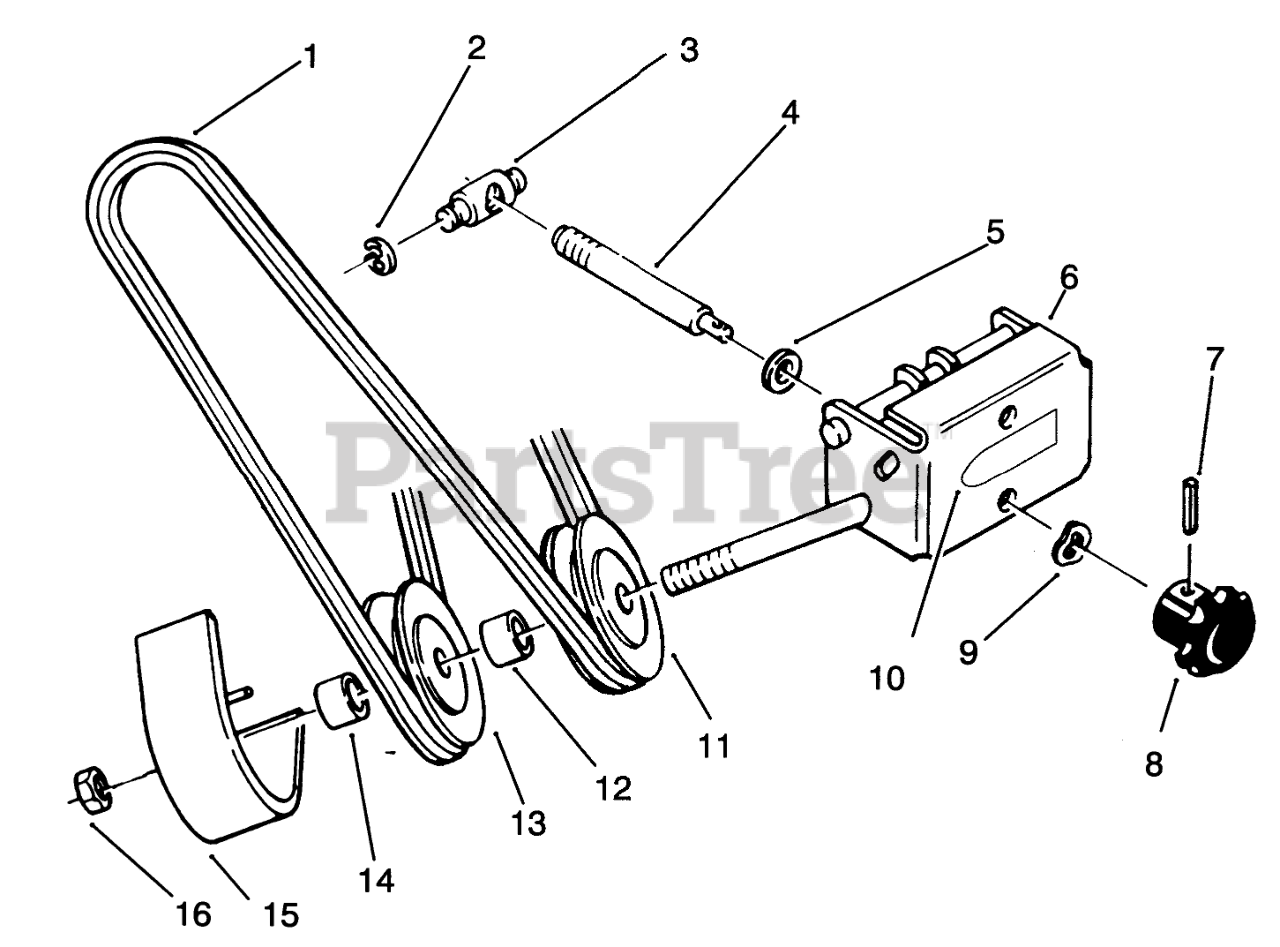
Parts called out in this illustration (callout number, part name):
1	V-BELT
2	RING-RETAINING
3	TRUNNION-DOUBLE
4	ROD ADJ
5	WASHER-FLAT
6	Front Support
7	PIN-ROLL
8	KNOB-ADJUSTMENT
9	WASHER-SPRING
10	Decal-Attac-O-Matic
11	Pulley-V
12	SPACER
13	PULLEY-FLAT IDLER
14	SPACER-OUTER
15	Belt Cover
16	Nut
